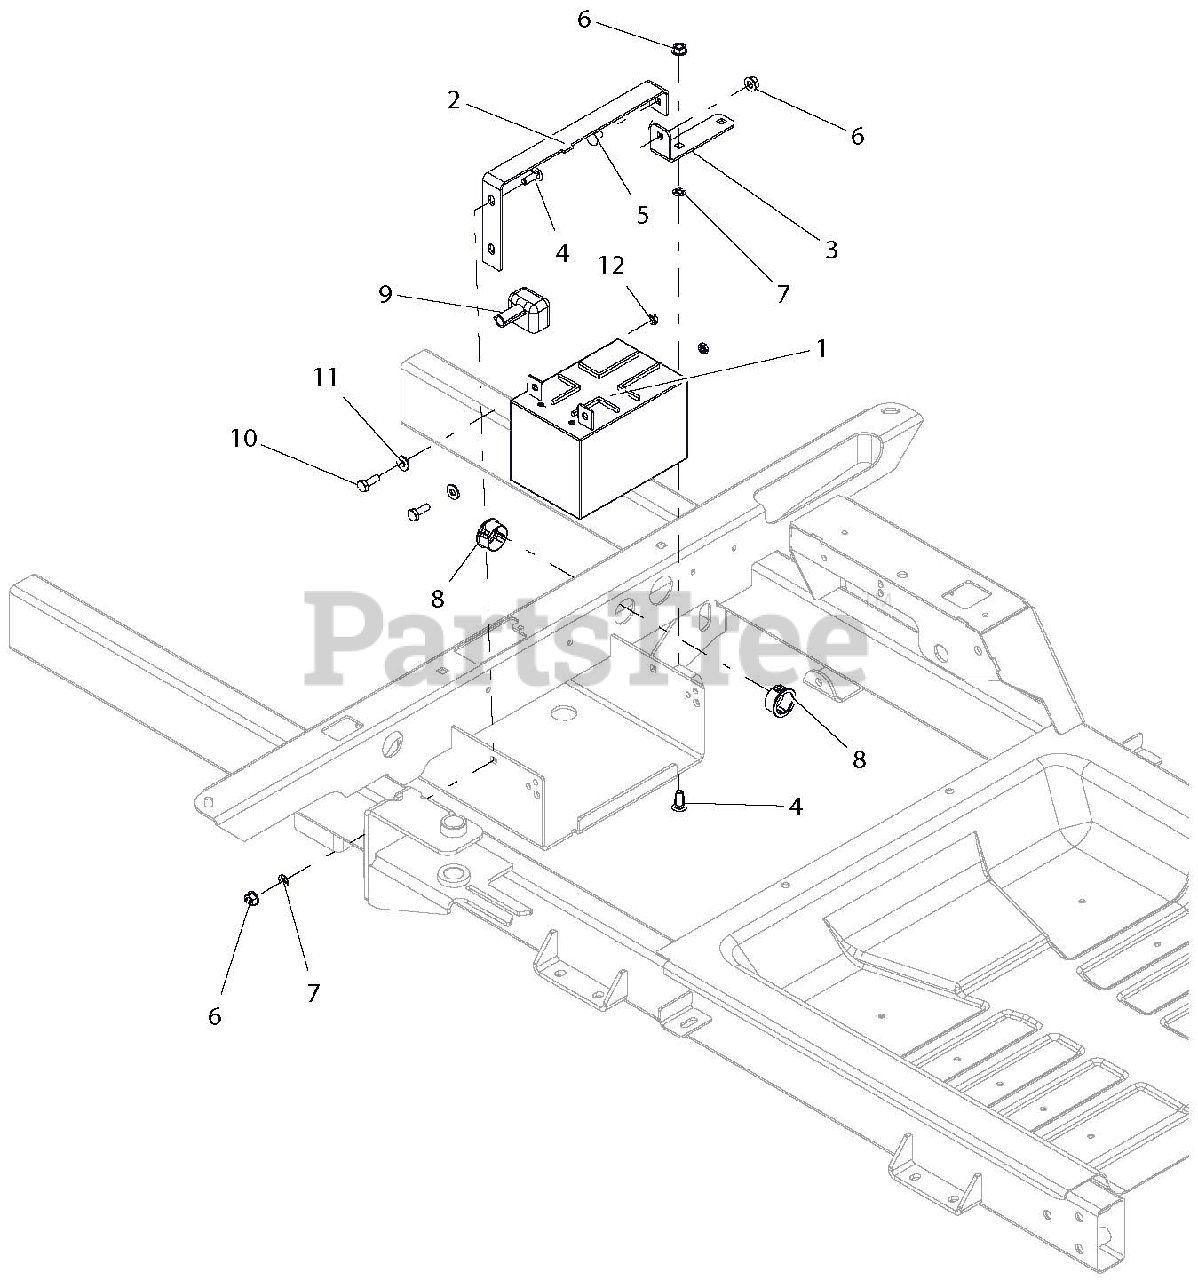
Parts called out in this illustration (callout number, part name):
1	BATTERY, 12V 12A-190CCA
2	BRKT, BATTERY HOLD-DOWN
3	BRKT, BATTERY HOLD DOWN
4	@BLT-RDHDSQNK .25-20X.75 G5YZ
5	@BLT-RDHDSQNK .25-20X.50 G5YZ
6	@NUT-LK-TOP-FLG .25-20 YWZC
7	NUT-PUSH .25X.50 O.D.
8	BSHG, PANEL SNAP .937X1.11X.56
9	INSULATOR
10	@BLT-HEX .25-20X.75 GR5 YWZC
11	@WSHR-FL-STL.281X.62X.065 YWZC
12	NUT, 10-24 KEPS
